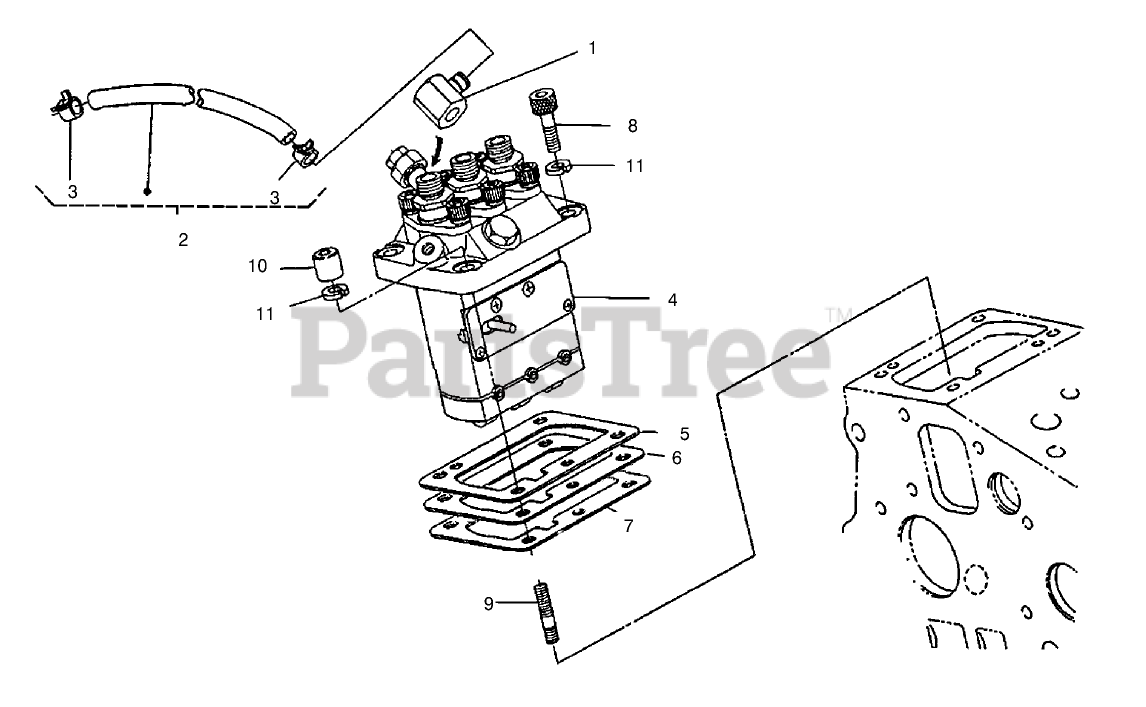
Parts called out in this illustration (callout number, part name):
1	JOINT-EYE
2	FUEL PIPE ASM
3	CLIP-PIPE
4	INJECTION PUMP ASM
5	SHIM-INJECTION (0.20MM)
6	SHIM-INJECTION (0.25MM)
7	SHIM-INJECTION (0.30MM)
8	BOLT-HSH
10	NUT-CAP
11	WASHER-SPRING
